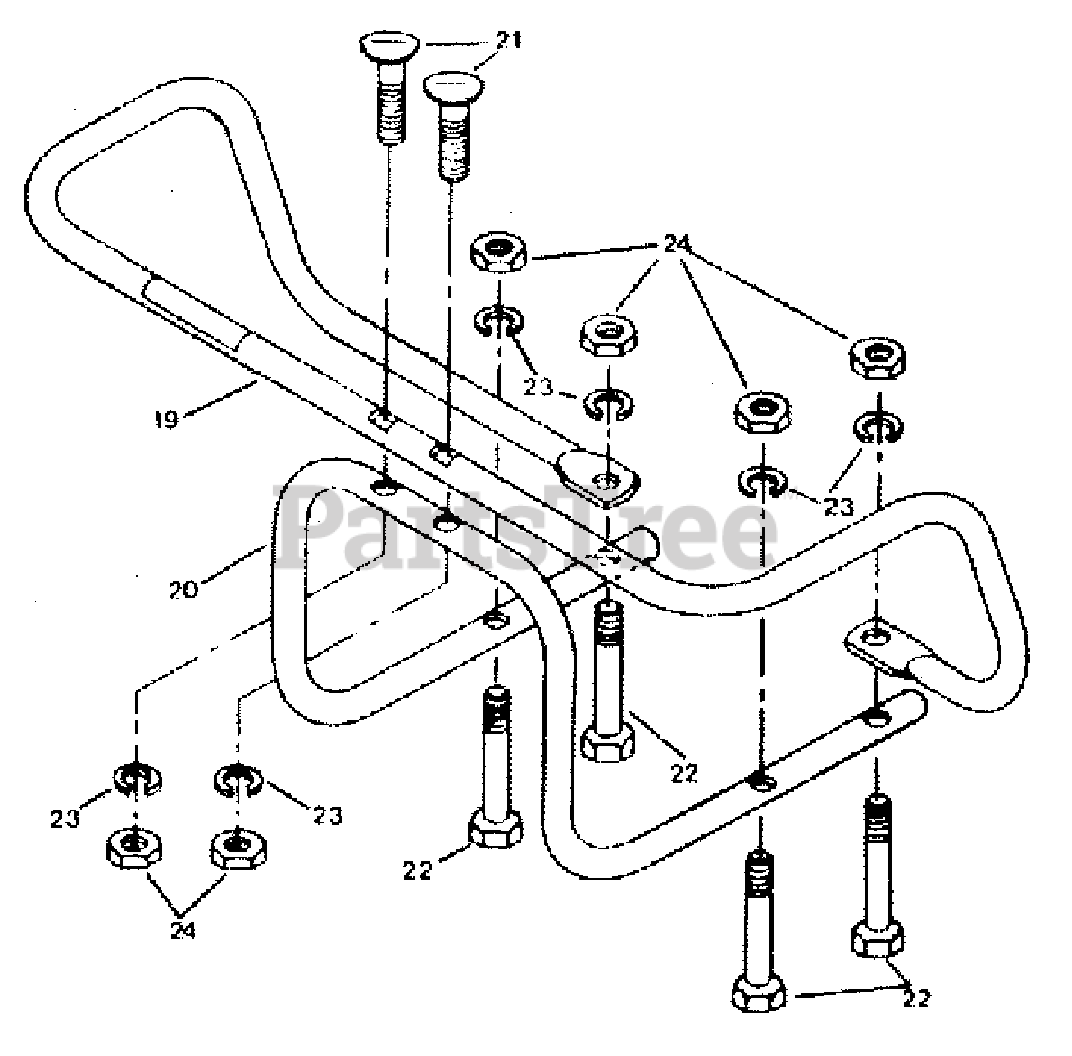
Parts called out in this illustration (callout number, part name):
19	Bumper-top section
20	Bumper-bottom section
21	Bolt-curved head, 5/16-18 x 2
22	Bolt-hex hd., 5/16-18 x 2-1/2",
23	lockwasher-5/16,
24	Nut-hex. 5/16-18,
